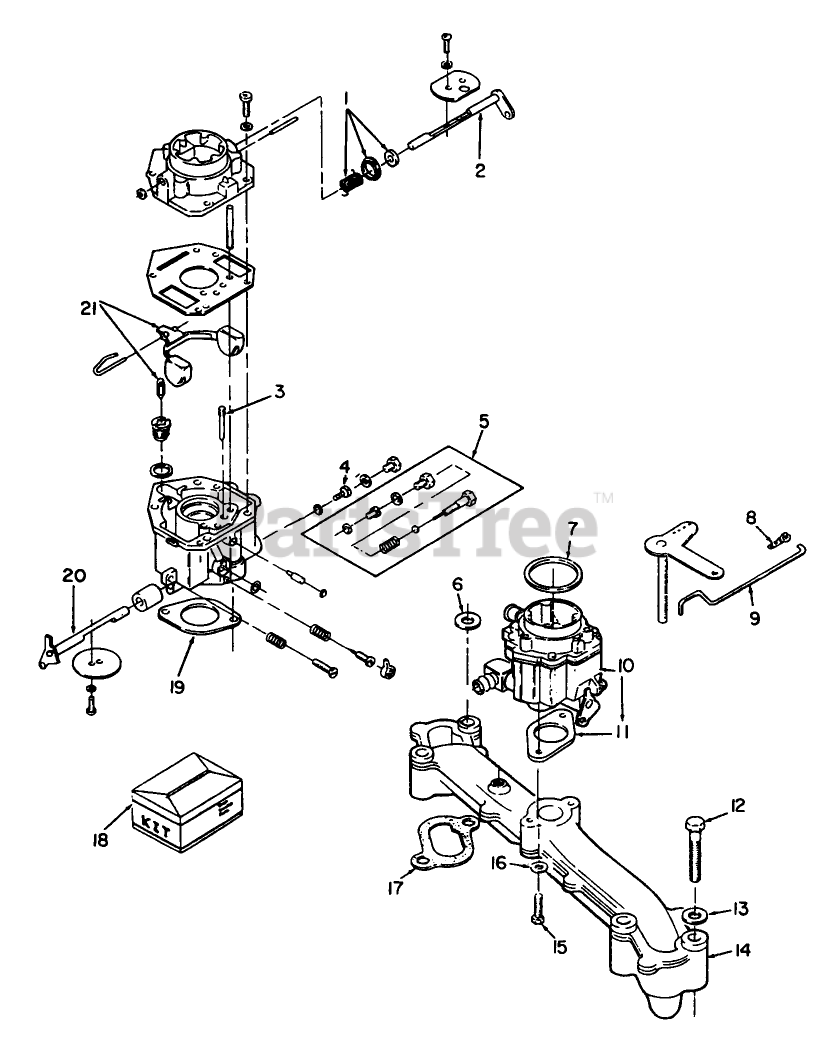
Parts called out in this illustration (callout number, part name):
1	CHOKE KIT LEVER
2	CHOKE KIT SHAFT
3	IDLE JET
4	POWER JET
5	Kit-Variable Jet
6	WASHER-PLAIN
9	CONTROL ROD
10	Carburetor-Complete
11	Gasket
12	SCREW-HH
13	WASHER-PLAIN
14	INTAKE MANIFOLD KIT
15	SCREW-HH
16	WASHER-FLAT
17	GASKET
18	Repair Kit
19	Gasket
20	Shaft-Throttle
21	FLOAT
